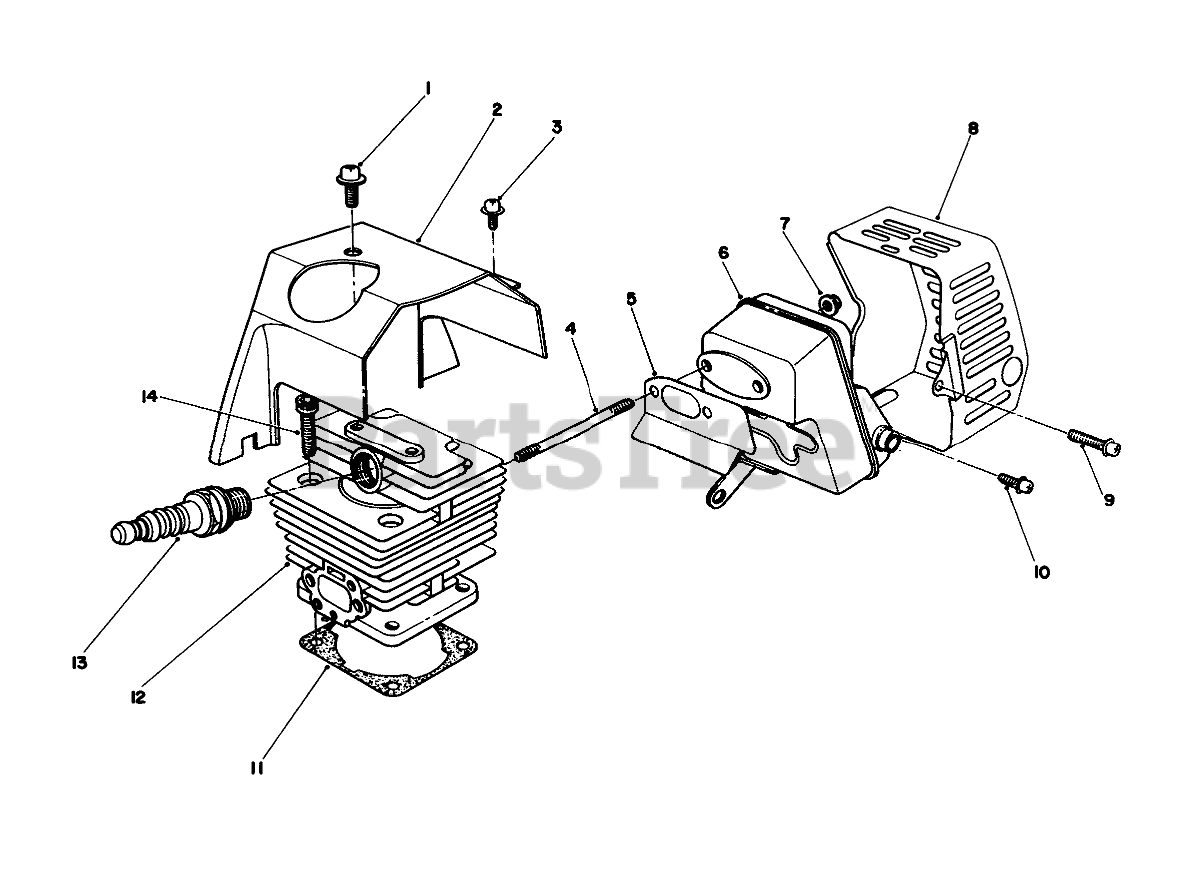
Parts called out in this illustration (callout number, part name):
1	Screw & Dishes
2	COVER,CYLINDER
3	Screw & Washer
4	BOLT,STUD
5	GASKET, MUFFLER
6	MUFFLER
7	NUT, FLANGE
8	COVER, MUFFLER
9	Screw & Washer
10	SCREW & WASHER
11	GASKET,CYLINDER
12	Cylinder (Incl. Ref. #4)
13	SPARK PLUG (NGK)
